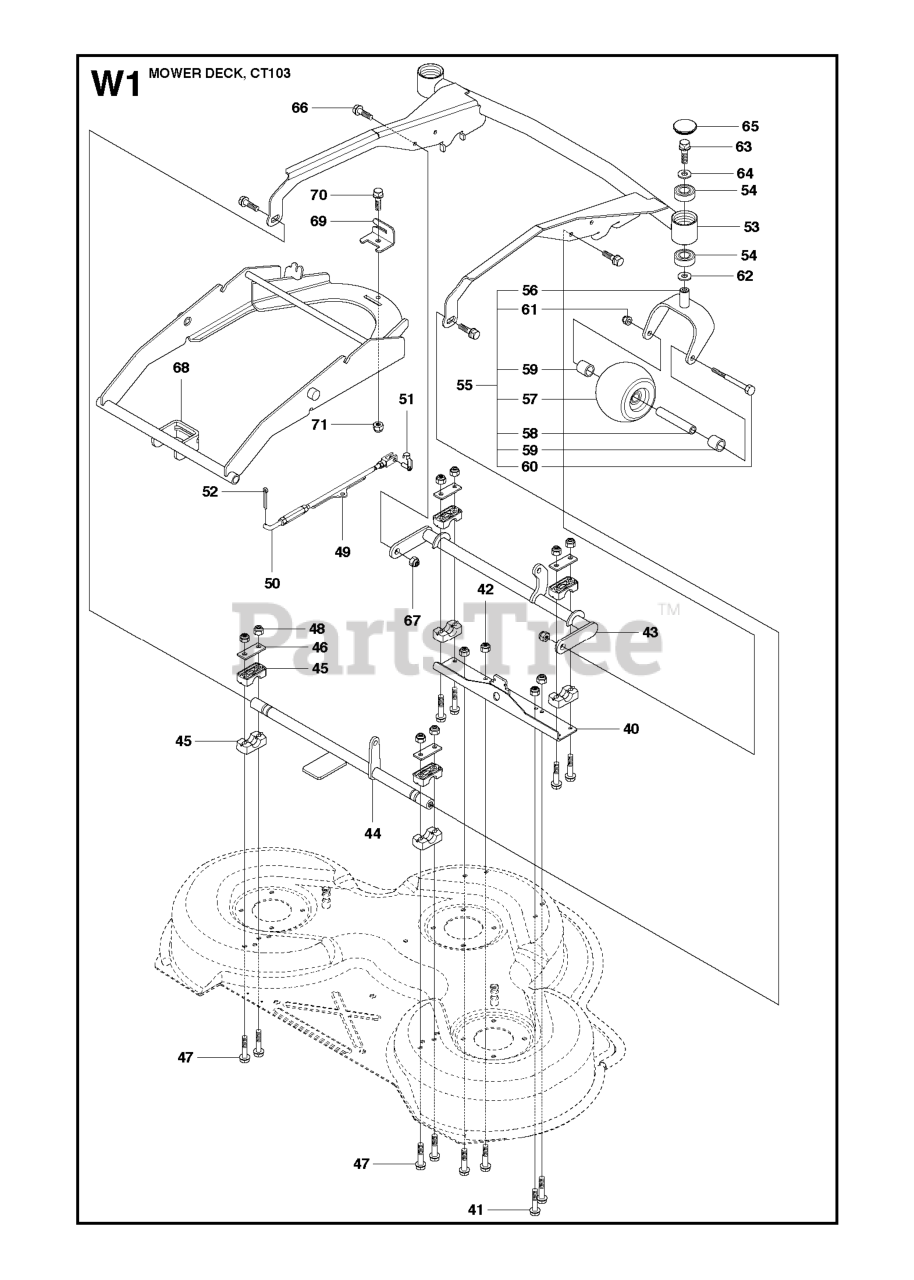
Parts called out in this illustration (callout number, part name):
42	LOCKNUT M8
48	LOCKNUT M8
50	PARALLEL ROD
54	BALL BEARING 6004-2RS1
55	PIVOT WHEELS
57	DECK ROLLER, FRONT
61	NUT
65	HUB CAP PIVOT WHEEL
67	LOCKNUT M8
71	LOCKNUT M8
